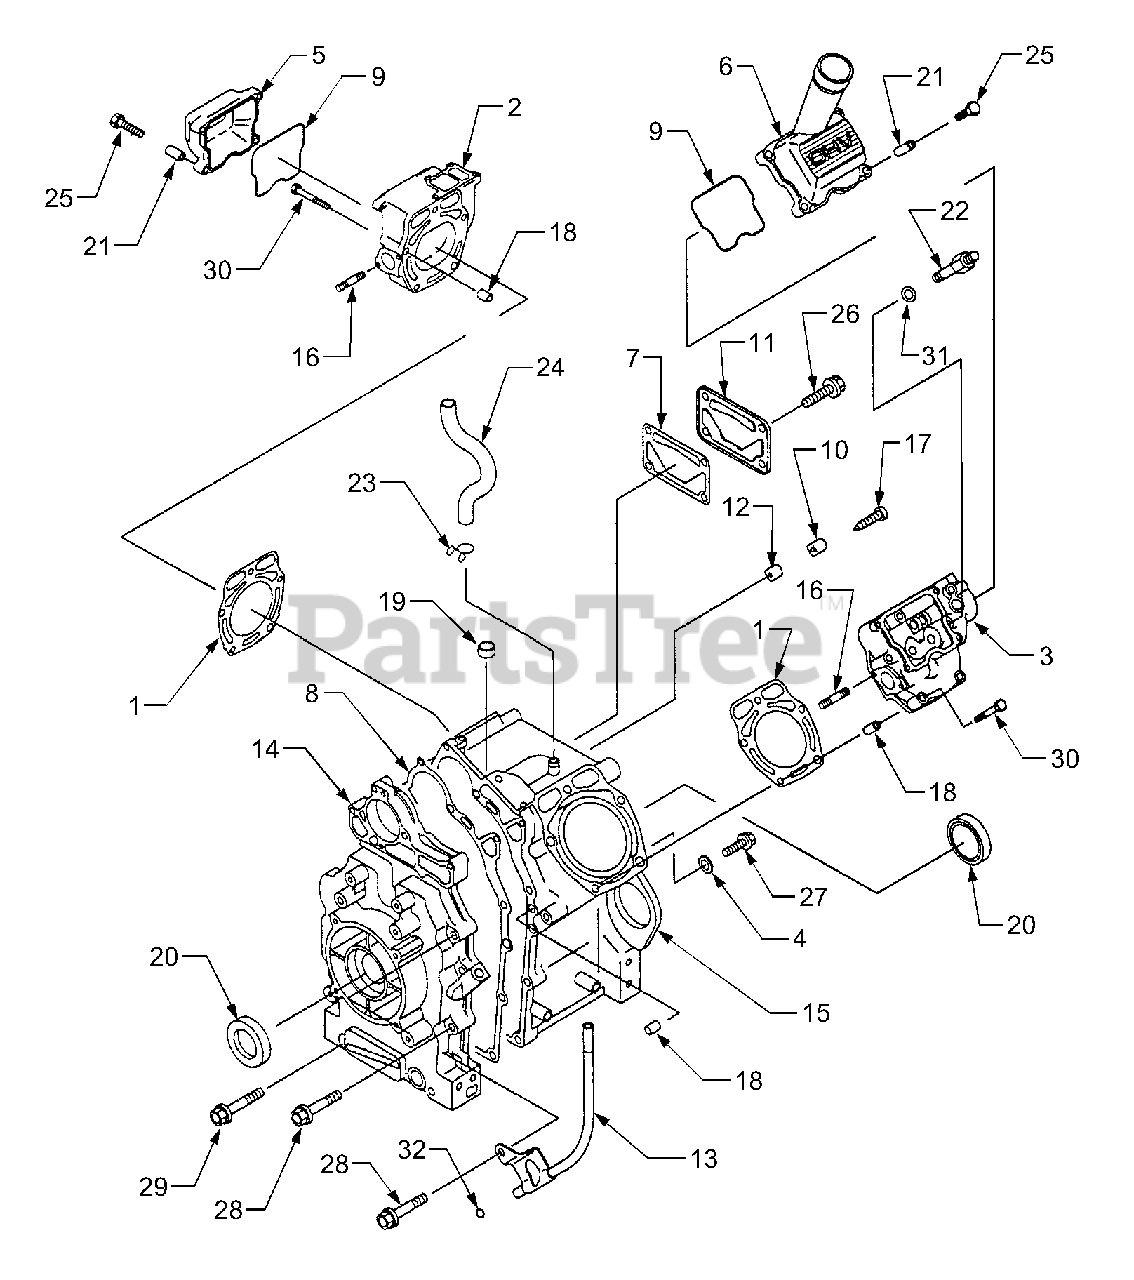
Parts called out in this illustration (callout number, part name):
2	Head, Complete Cylinder
3	Head, Complete Cylinder
6	Cover, Valve w/Oil Fill
7	Gasket, Cover
8	Gasket, Crankcase Cover
9	Gasket, Valve Cover
13	Pipe, Oil Gauge
14	Cover, Crankcase
15	Crankcase Complete
18	Pin, Dowel, M10 x 8.2 x 14
20	Seal, Oil
25	Bolt, Flanged, M6 x 25
26	Bolt, Flanged, M8 x 16
27	Bolt, Flanged, M8 x 12
28	Bolt, Flanged, M8 x 45
29	Bolt, Flanged, M8 x 60
30	Bolt, Flanged, M8 x 65
31	Washer, Plain, 8MM
32	O-Ring, 10MM
